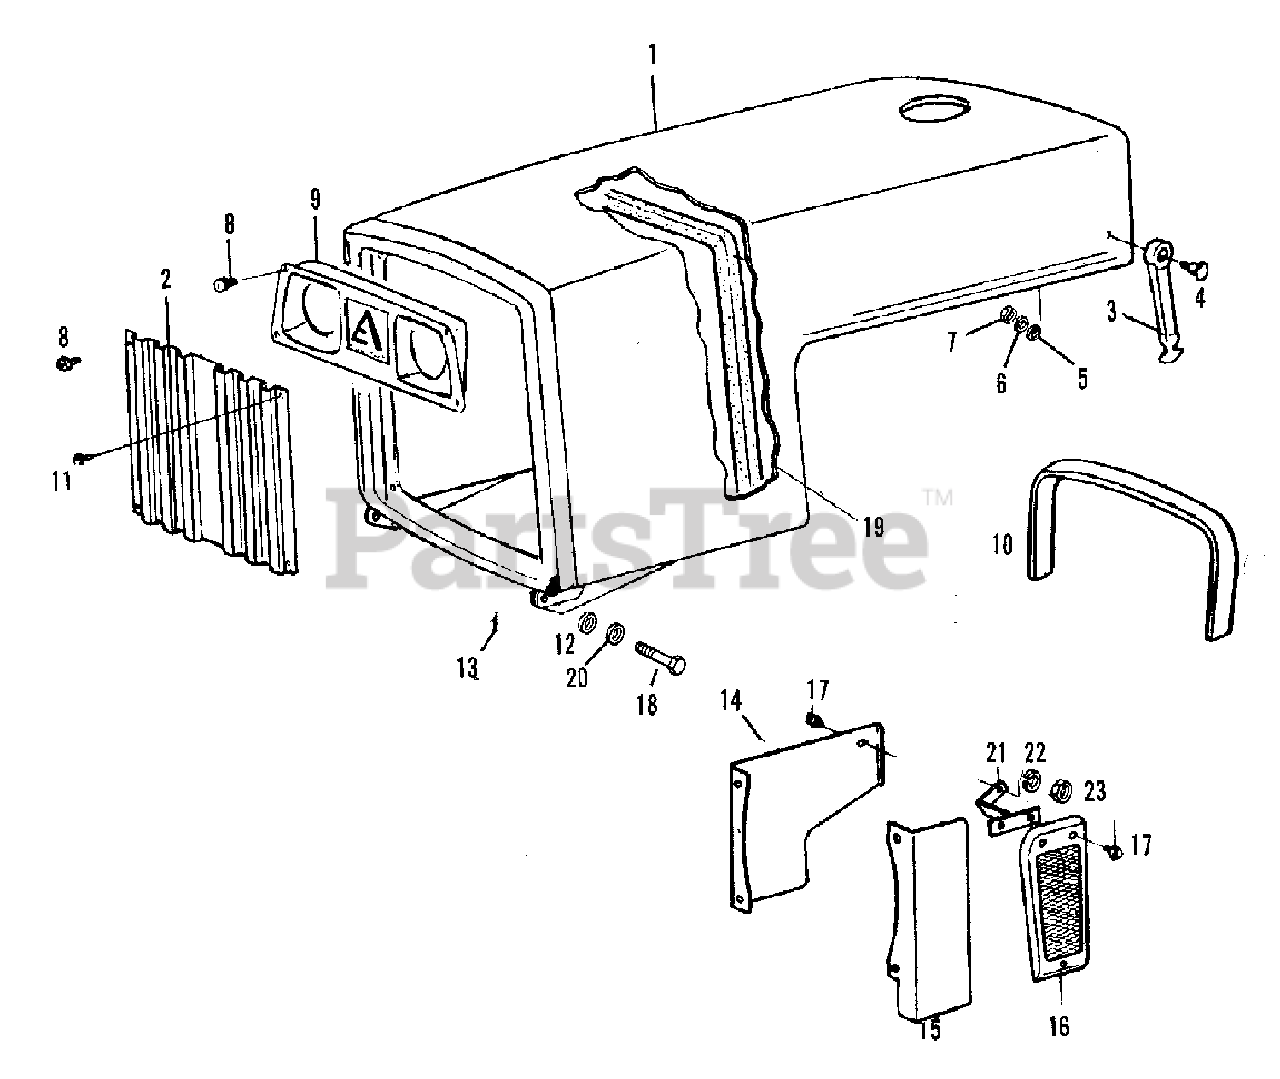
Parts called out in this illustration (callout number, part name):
4	BOLT, catcher
5	WASHER, M6
6	LOCKWASHER, M6
9	PANEL, headlight
13	PIN, cotter
14	COVER, safety R.H.
16	COVER, safety L.H.
17	CAPSCREW, M8 x 16
20	LOCKWASHER, M12
22	LOCKWASHER, M10
